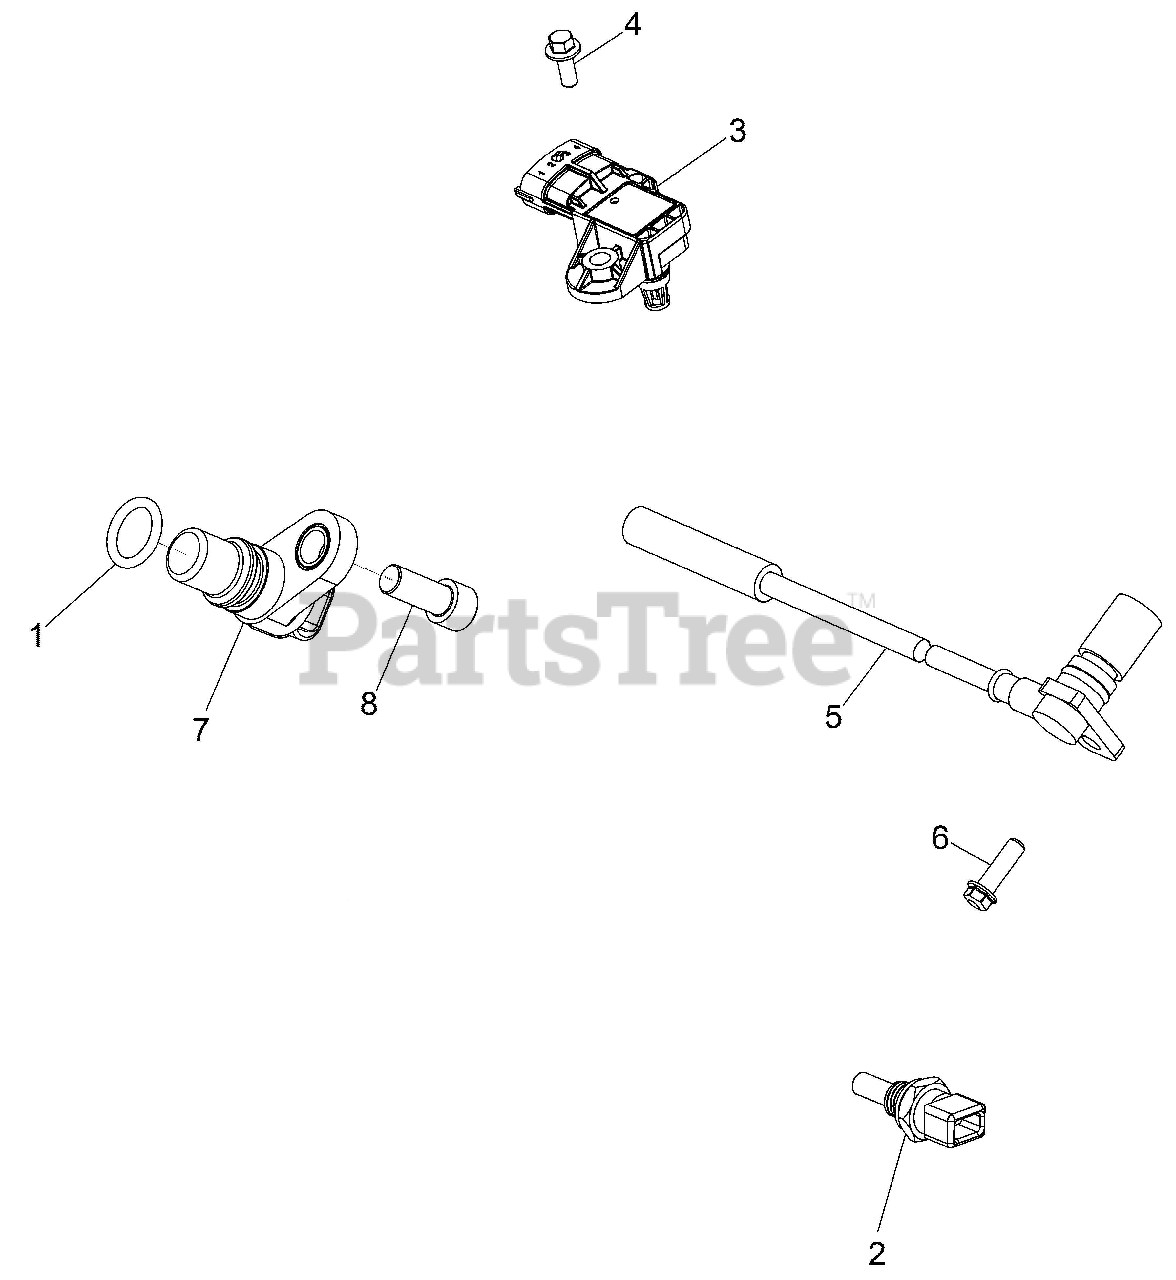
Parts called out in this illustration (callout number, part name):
1	O-RING, -113
2	SENSOR-THERMISTER
3	SENSOR-TMAP DSS3-TF
5	SENSOR-CRANK POSITION
6	SCR-M6X20,HXFLG,0600214
7	SENSOR-SPEED,TRANS
